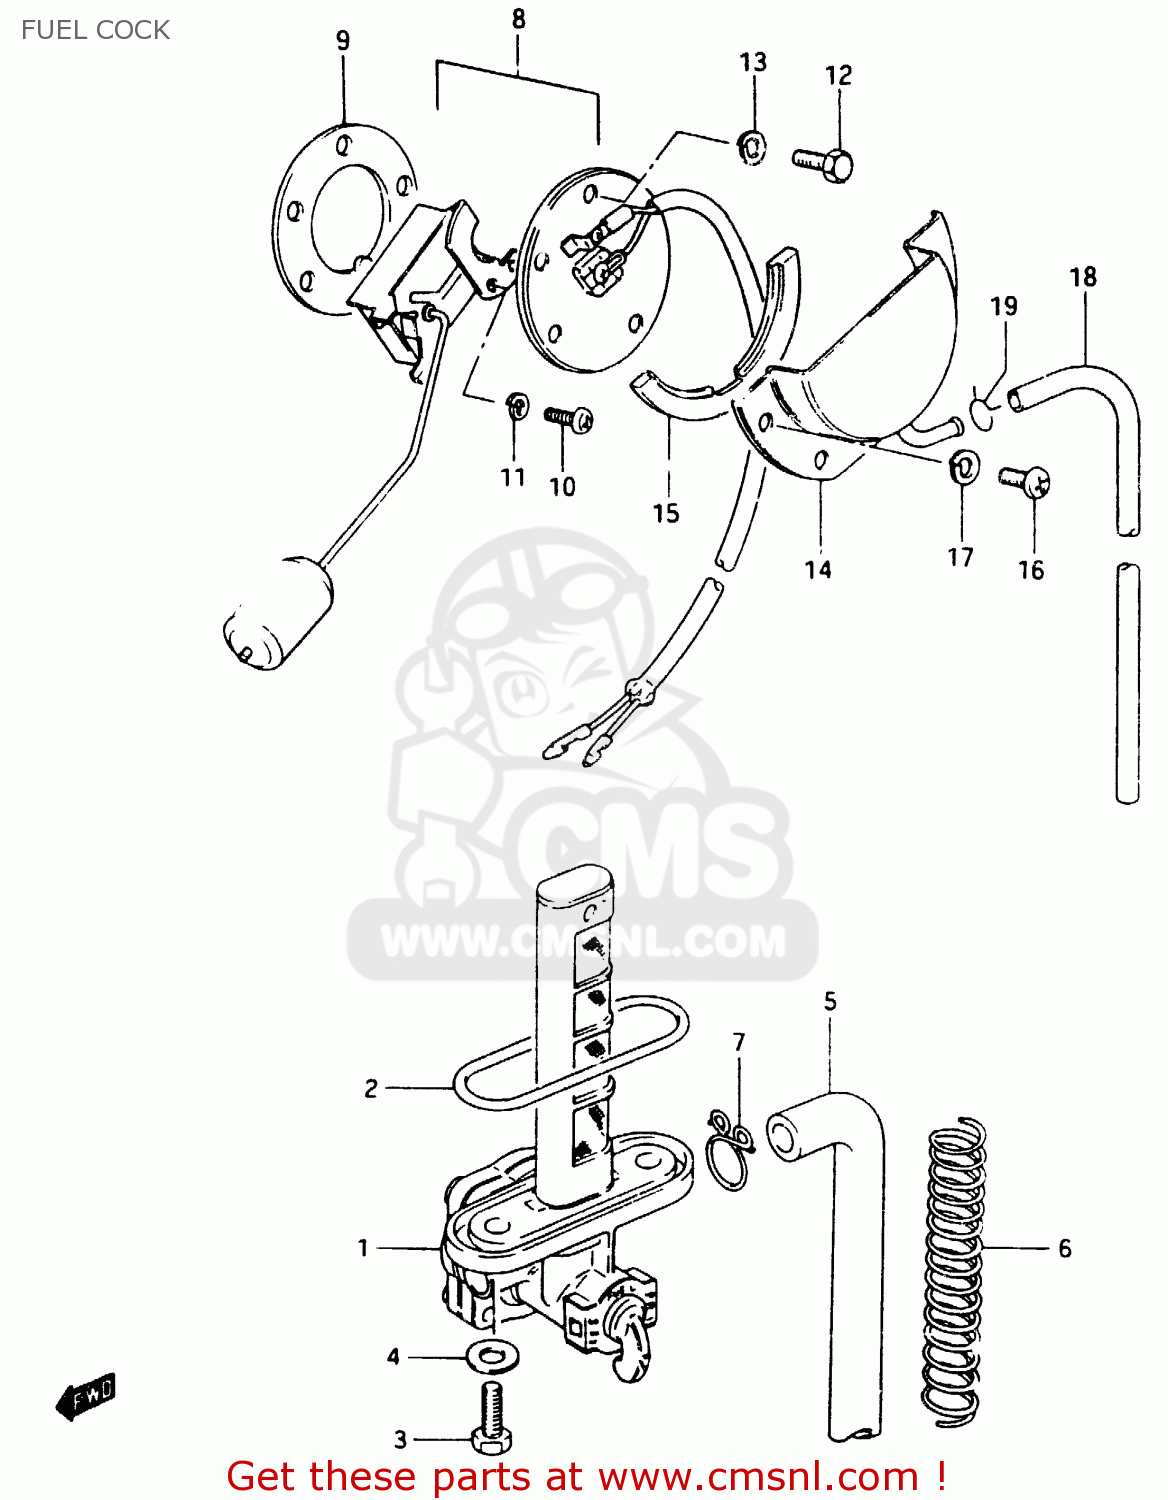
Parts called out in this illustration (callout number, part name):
1	COCK ASSEMBLY,FUEL
2	O RING
3	BOLT(6X20)
4	GASKET
5	HOSE
6	SPRING
7	CLIP
8	GAUGE ASSEMBLY,FUEL LEVEL
9	GASKET,FUEL LEVEL GAUGE (NAS)
10	SCREW 5X10
11	LOCK WASHER
12	BOLT
13	LOCK WASHER
14	PLATE,FUEL DRAIN
15	GASKET (NAS)
16	SCREW
17	LOCK WASHER
18	HOSE,FUEL
19	CLIP
